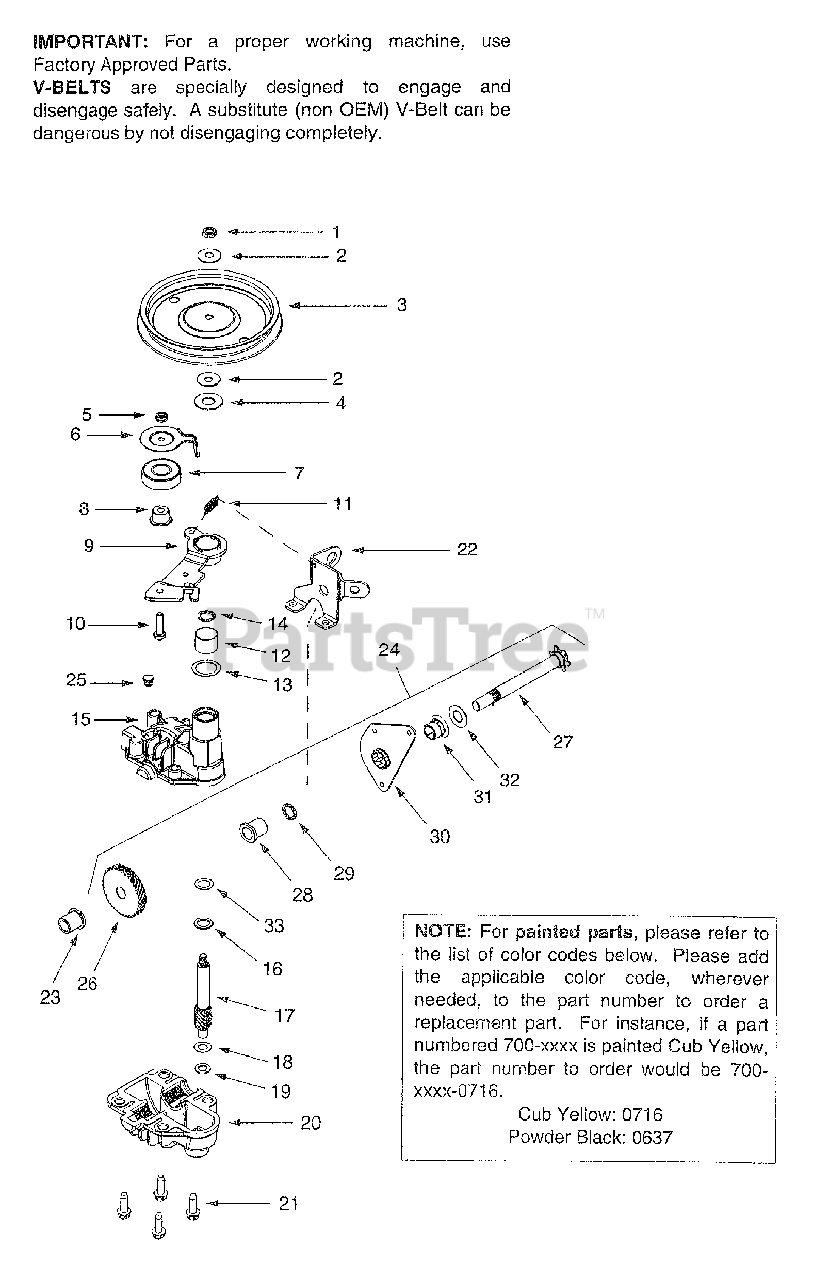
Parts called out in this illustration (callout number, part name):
1	Hex Jam Nut, 5/16-24
2	Bell Wash. .325 x .930 x .045
4	Fl. Wash. .510 x 1.120 x .060
5	Hex Jam Nut, 1/4-28
6	Belt Keeper
7	Bearing
8	Flange Spacer
9	Idler Bracket Assembly
10	Hex Cap Scr. 1/4-28 x 1.00 Gr. 5
11	Extension Spring
12	Bearing Sleeve
13	Fl. Wash. .885 x 1.145 x .030
14	Oil Seal
15	Upper Housing Assembly
16	Thrust Wash. .504 x .700 x .030
17	Pinion Shaft, 10 T.
18	Thr. Wash. 3/8 x .70 x .030
19	Thr. Wash. .388 x .625 x .062
20	Lower Housing Assembly
21	Hex Scr. 1/2-20 x .75
24	Shaft Assembly
26	Gear 34 T.
27	Output Shaft, 6 T.
28	Flange Bearing
29	Oil Seal
30	Pivot Bracket
31	Flange Bearing
32	Flat Washer
